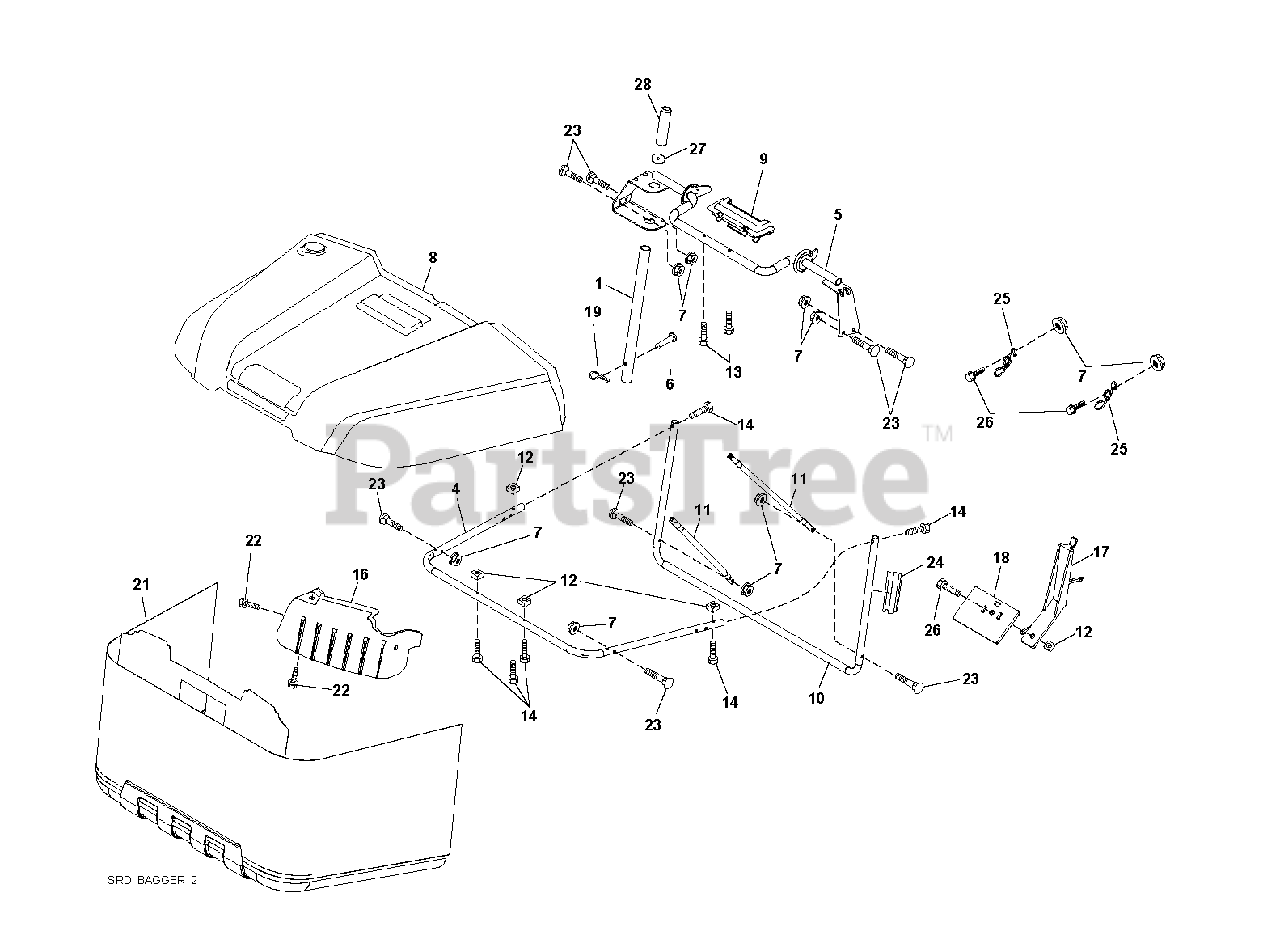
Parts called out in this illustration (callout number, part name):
1	TUBE HANDLE
6	RIVET,DRILLED
7	NUT T
19	RETAINER-SPRNG RB
22	SCREW.HI-LO.CONSOLE
26	SCREW HEX CRT
28	GRIP.HANDLE.BLACK
